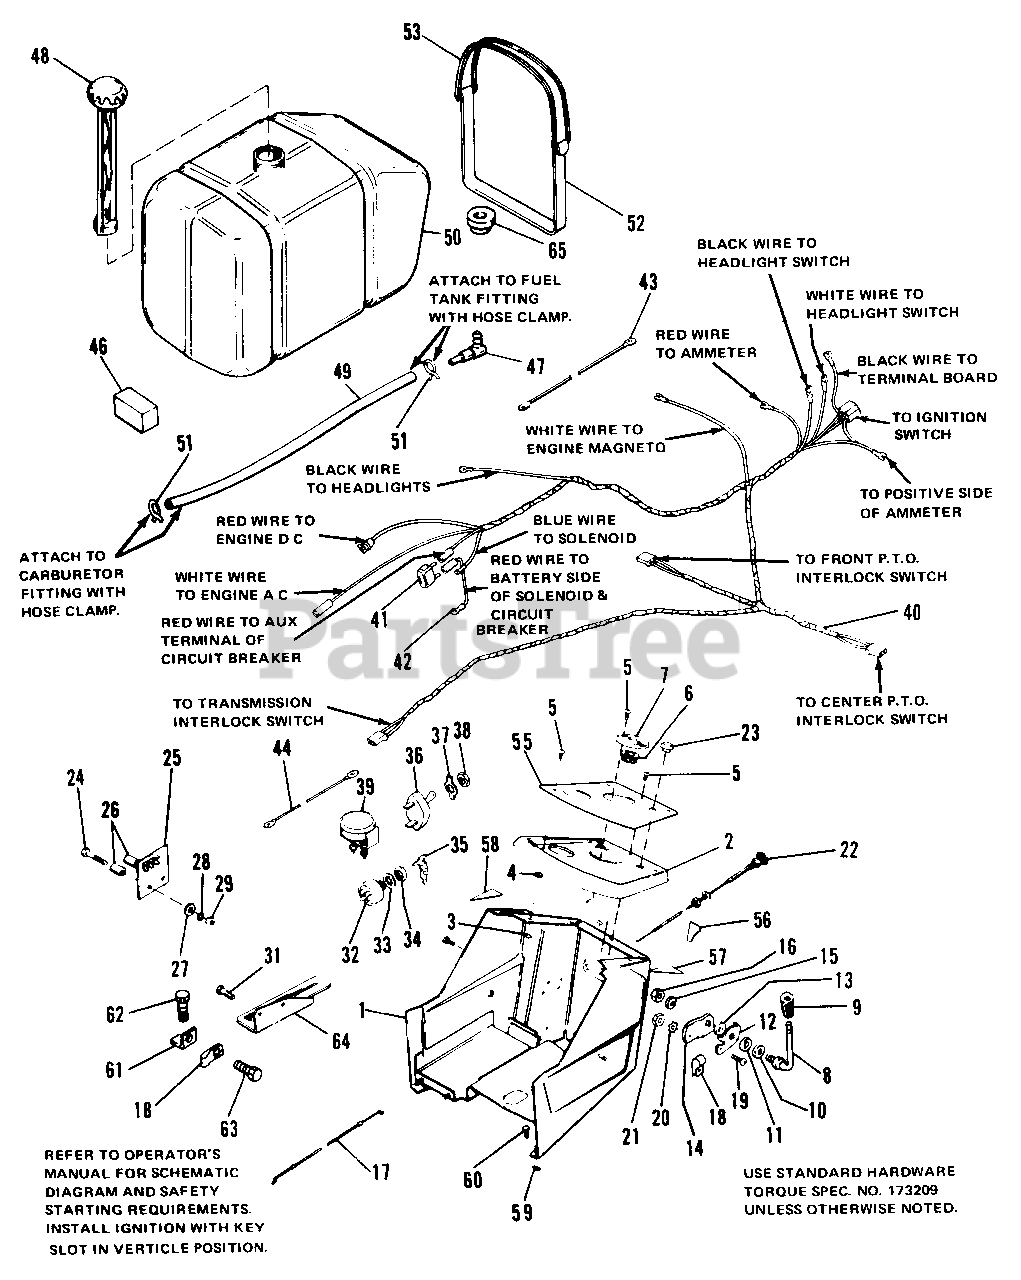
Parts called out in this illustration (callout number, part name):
1	DASH ASSEMBLY
2	PANEL, Instrument
3	NUT, Retainer, Tinn.
4	WASHER, Plain, 3/16
5	SCREW, Mach. Rd. Hd., 1/4-20 x 1/2
7	PLATE STEERING, Adj.
8	HANDLE, Clutch Control
9	KNOB, Tapered
12	STOP, Throttle Kit (inc. ref. 10, 11)
14	ARM, Throttle
15	LOCKWASHER, Dished Shakeproof, 3/8
16	LOCKNUT, Hex, 3/8-16
17	CONTROL, Throttle
18	CLIP, Bowden Wire
19	SCREW, Rd. Hd., No. 10-32 x 1/2
20	LOCKWASHER, External, No. 10
21	NUT, Mach. Hex, No. 10-32
22	CONTROL, Choke
23	PLUG, Button
24	CAPSCREW, Hex Hd., 1/4-20 x 1-1/4
25	BOARD, Terminal
27	WASHER, Flat, 1/4
28	LOCKWASHER, Shakerproof, 1/4
29	NUT, Hex, 1/4-20
31	SCREW, Special
32	SWITCH, Ignition
33	LOCKWASHER, Internal, 5/8
34	NUT, Hex Special
35	KEY & RING ASSEMBLY
36	SWITCH, Toggle
37	PLATE
38	NUT
40	(00000-(02550) HARNESS ASSEMBLY
40	(02551) HARNESS ASSEMBLY
41	CIRCUIT BREAKER
42	WIRE ASSEMBLY
43	WIRE ASSEMBLY
44	WIRE ASSEMBLY, Light Switch
46	PAD, Fuel Tank
47	FITTING, Gas Tank
48	CAP, Fuel Tank
50	TANK ASSY, Fuel, Inc. Ref. No's 47, 49, 65 & 51
51	CLAMP, Hose
52	STRAP, Tank
53	STRAP, Fuel Tank
55	DECAL, Instrument Panel
56	DECAL, Ignition
57	DECAL, Throttle Control
58	DECAL, Shuttle Control
59	NUT, Speed, Tinn.
60	SCREW, Hex Hd. Thd. Forming, No. 14 x 3/4
61	BRACKET, Cable
62	SCREW, Hex Hd., 1/4-20 x 5/8
63	SCREW, Taptite, No. 10-24 x 1/2
66	CLIP, Cable
